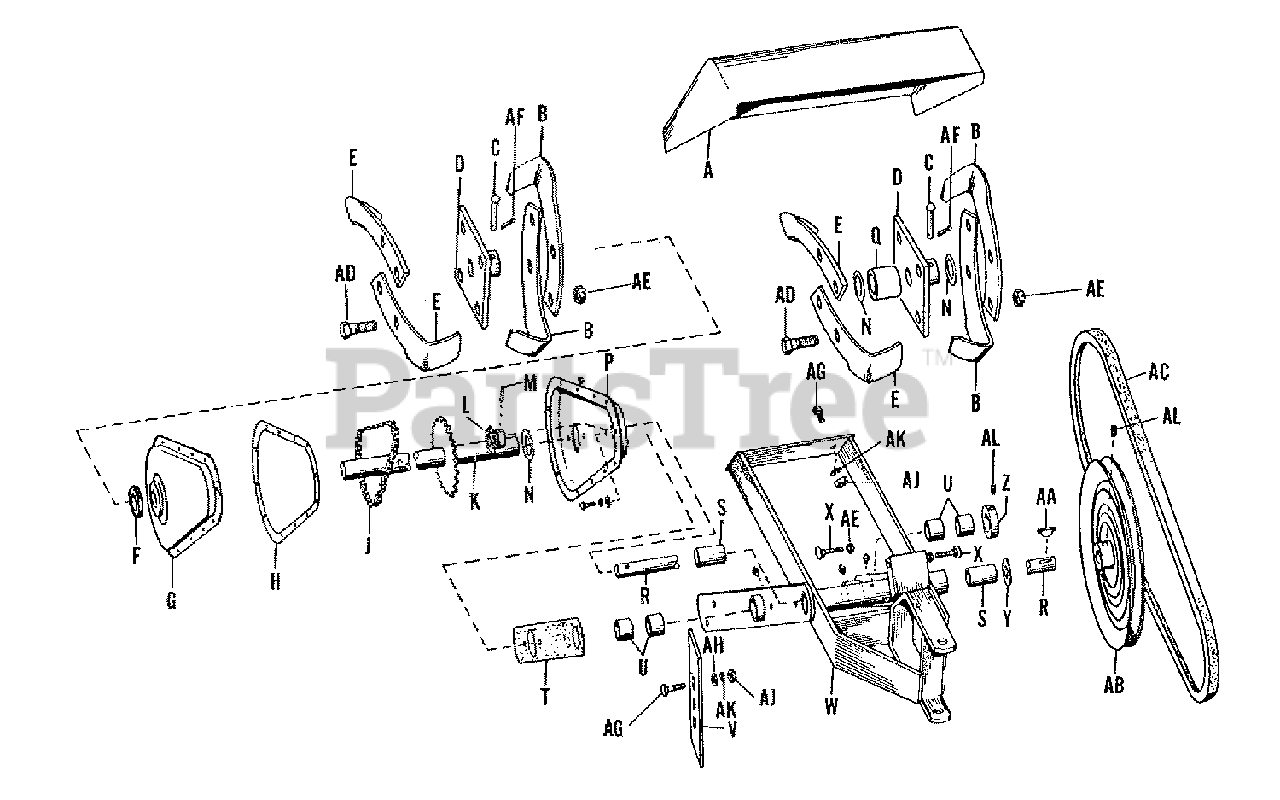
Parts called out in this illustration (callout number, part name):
B	R.H. TINE BLADE
C	PIN - Tine Plate Assembly
D	TINE PLATE ASSEMBLY
E	L.H. TINE BLADE
G	GUARD ASSEMBLY
H	GUARD GASKET
J	DRIVE CHAIN
K	TINE SHAFT ASSEMBLY
L	DRIVE SPROCKET
M	ROLL PIN (Two Pins Assembled)
P	CHAIN GUARD, Half
R	DRIVE SHAFT
S	DRIVE SHAFT BEARING
T	FRAME GASKET
U	TINE SHAFT BEARING
W	FRAME ASSEMBLY
X	SCREW ASSEMBLY- Adjustment
Y	DRIVE PULLEY WASHER
AA	HI-PRO KEY, H. P-706
AB	DRIVE SHEAVE
AC	V" DRIVE BELT, 76
AD	CAPSCREW, Large, 7/16"-20 NF x 3/4"
AE	NUT, Hex Full, 7/16"-20 NF
AF	SPRING CLIP
AG	CAPSCREW, 7/16"-20 NF x 3/4" Hex Head, Large
AH	WASHER, Plain, 3/8"
AJ	NUT, Full Hex, NC 3/8"-16
AK	LOCKWASHER, 5/16"
AL	SETSCREW, Large, 5/16"-18 NC x 3/8"
